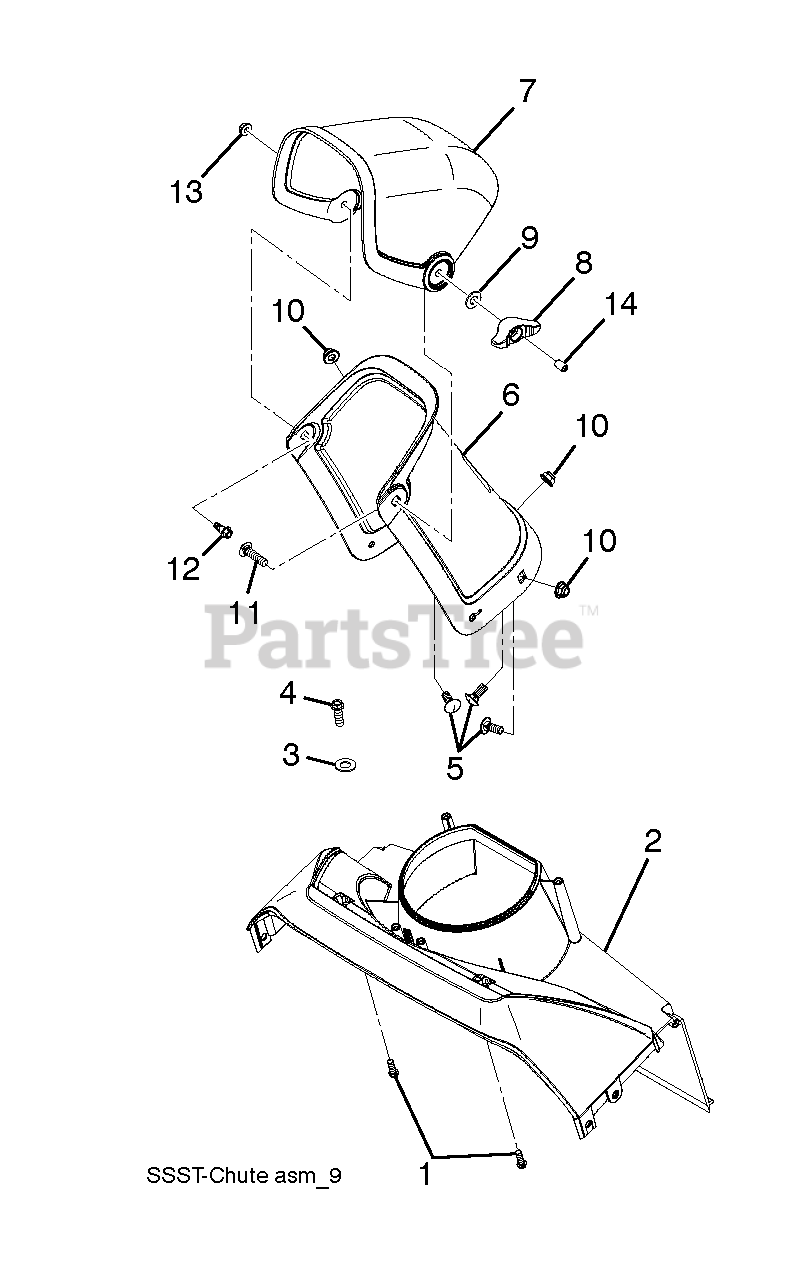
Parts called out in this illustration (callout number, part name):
1	SCREW.HX.13X.750
2	AUGER.PLENUM.SINGLE.STAGE.GREY
3	WASHER
4	BOLT.HEX.HD.WASHER.5/16-18X.75
5	BOLT.RH.SQNK.5/16
6	CHUTE.DISCHARGE.MAIN.GRAY
7	DEFLECTOR.SNOW.GREY
8	KNOB, DEFLECTOR
9	WASHER,HARDEN
10	LOCKNUT-FLANGE 5/16-18
11	BOLT.CARRIAGE.5/16-18
12	BOLT.SHOULDER.HEX.HD.1/4-20
14	PLUNGER CAP
